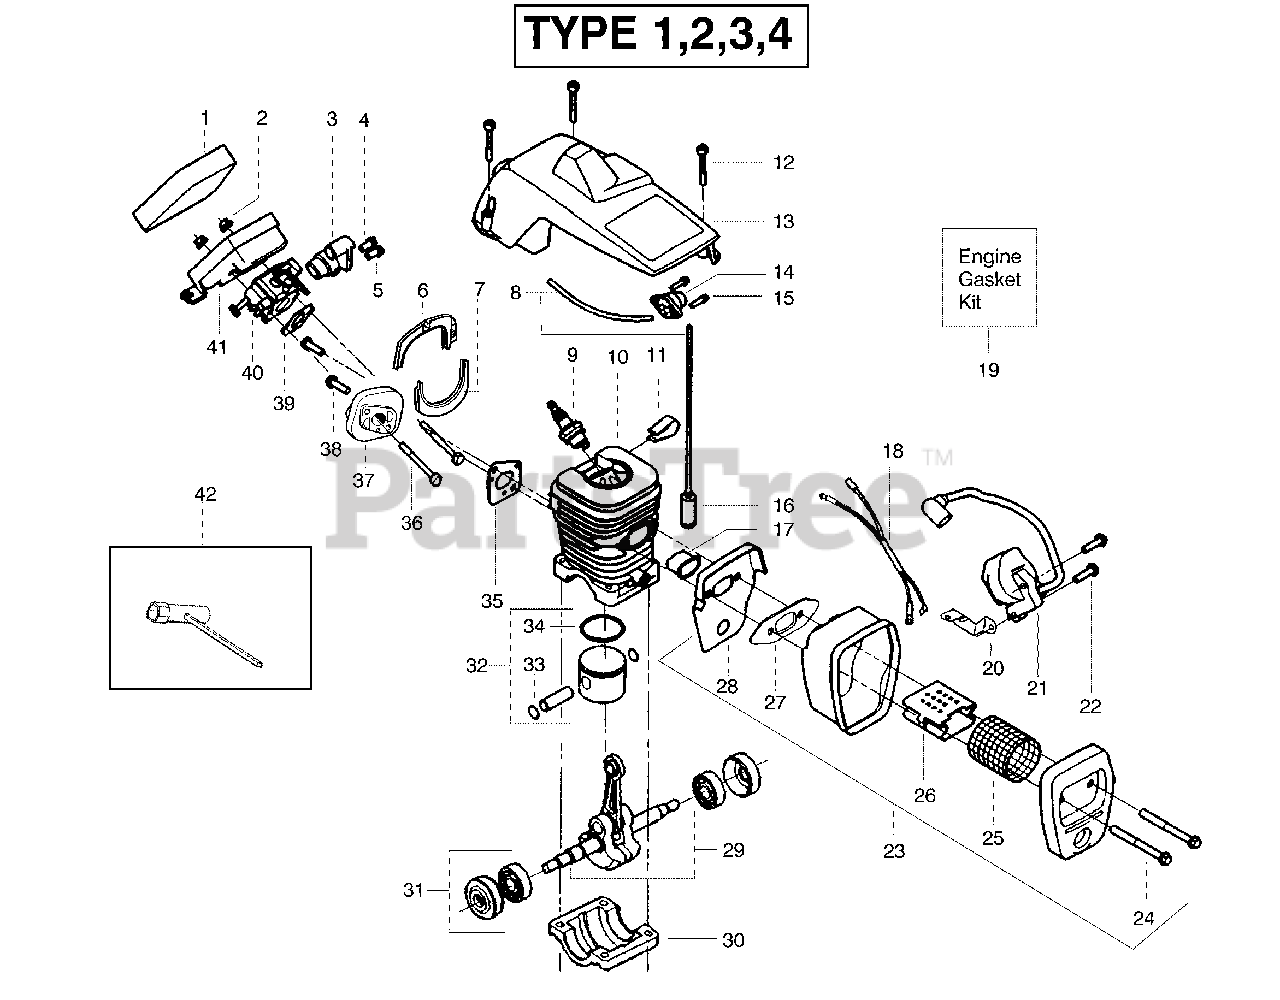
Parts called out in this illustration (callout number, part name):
1	Foam - Air Filter
3	Grommet-Carb Adjust
4	Limiter Cap-High (red)
5	Limiter Cap-Low(blue)
6	Seal-Carb Adapter
7	Seal-Carb Adapter
8	Kit-Fuel Line (Small)
9	Spark Plug (RCJ-7Y)
10	Kit-Cylinder
11	Clip-High Tension Lead
13	Shield-Cylinder 2075
13	Shield-Cylinder 2075c
13	Shield-Cylinder 2075oc
14	Assy - Air Purge
16	Assy-Fuel Pick-up
17	Insulator-Heat
18	Assy. -Wire Harness
19	Kit-Engine Gasket
20	Strap-Ground
21	Module- Ignition
23	Assy-Muffler
25	Screen-Spark
26	Diffuser-Muffler
27	Gasket-Muffler
28	Backplate-Muffler
29	Assy. - Crankshaft
30	Cap-Crankcase
31	Assy.-Seal & Bearing
32	Kit-Piston
33	Retainer-Piston Pin
34	Ring - Piston
35	Gasket - Carb. Adapter
37	Adapter - Carb. 2075 (Kit)
39	Gasket - Carburetor
40	Kit-Carburetor
41	Housing- Air Filter
42	Wrench - Bar
